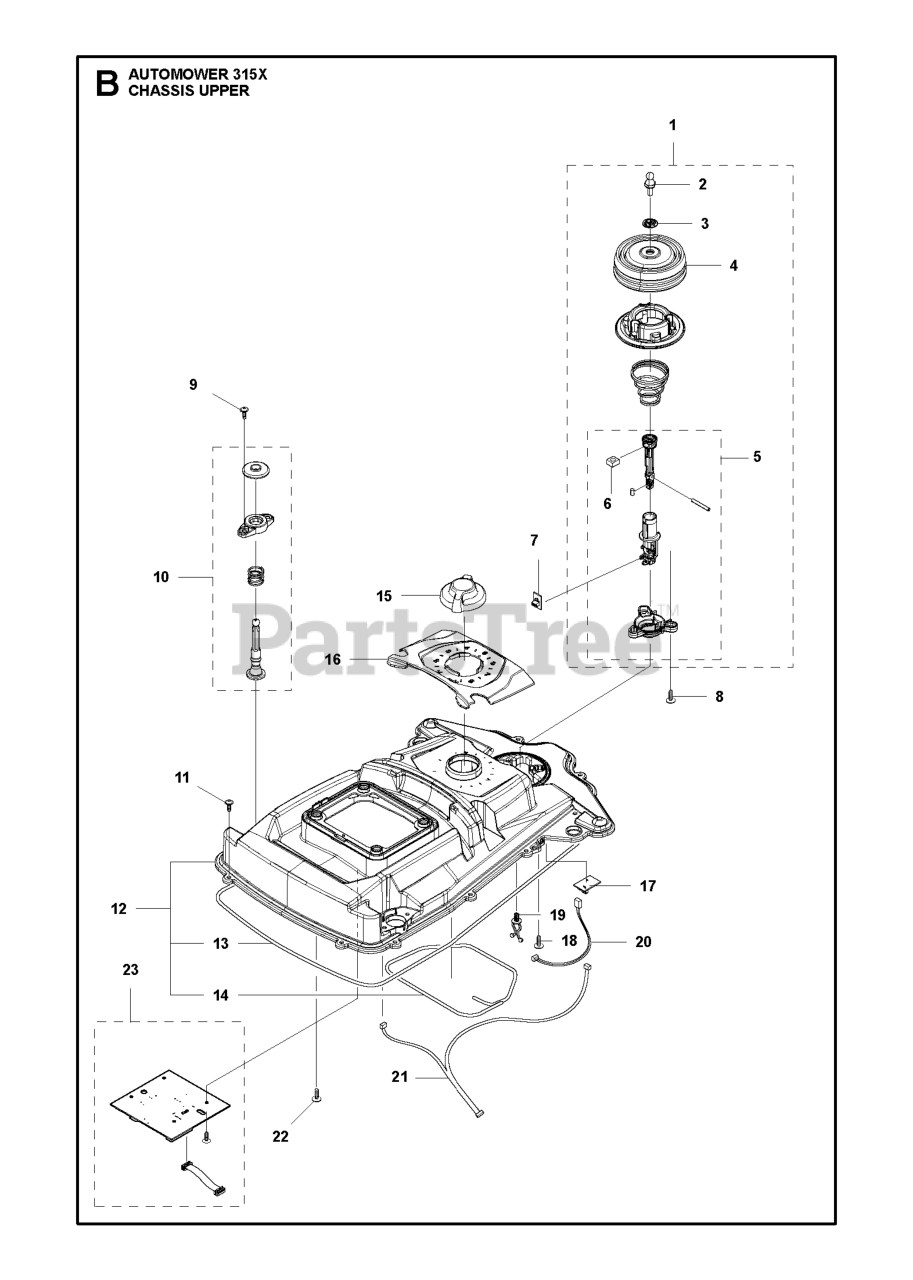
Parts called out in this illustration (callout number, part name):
1	JOYSTICK KIT
2	STUD SNAPLOC
3	WASHER JOYSTICK
4	BELLOWS LIFT-COLLISION
5	JOYSTICK KIT
6	NUT
7	PRINTED CIRCUIT ASSY PCBA LIFT
8	SCREW 14MM
9	SCREW ITXPANT
10	JOYSTICK ASSY REAR
11	SCREW ITXPANT
12	CHASSIS KIT
13	SEALING STRIP P 15 CHASSI LOW
14	SEALING STRIP P15 UPPER
15	KNOB HVA GREY
16	PLATE HEIGHT ADJUSTMENT
17	PRINTED CIRCUIT ASSY COLLISION
18	SCREW ITXPANT
19	HOLDER TWIST LOCK
20	LOOM LIFT, COLLISION
21	WIRING ASSY HMI
22	SCREW ITXPANT
23	CONNECT MODULE 2G / 3G
